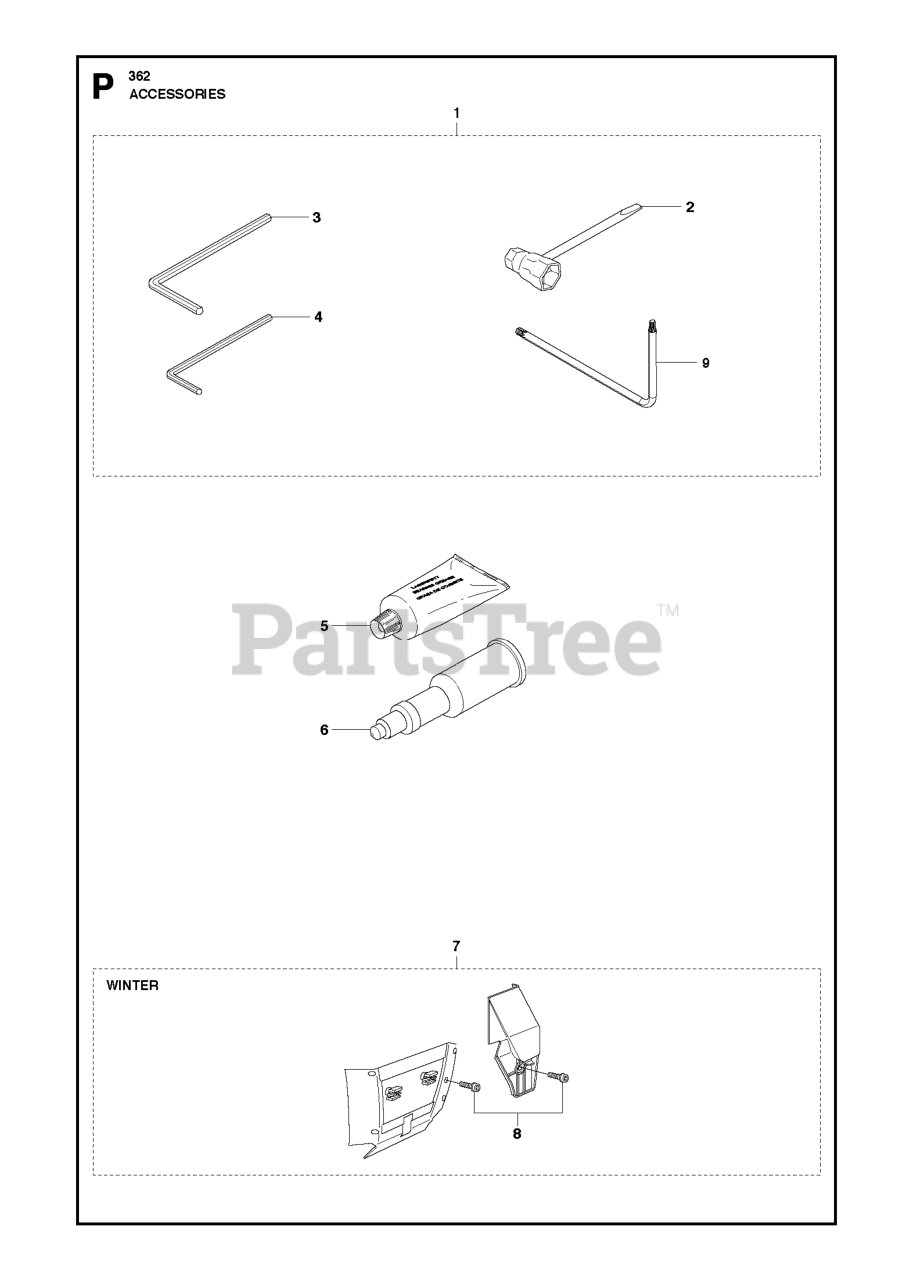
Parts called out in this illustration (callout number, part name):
2	COMBI TOOL
3	L-SPANNER
4	L-SPANNER
5	GREASE
6	Grease Gun
7	WINTER KIT
9	WRENCH
